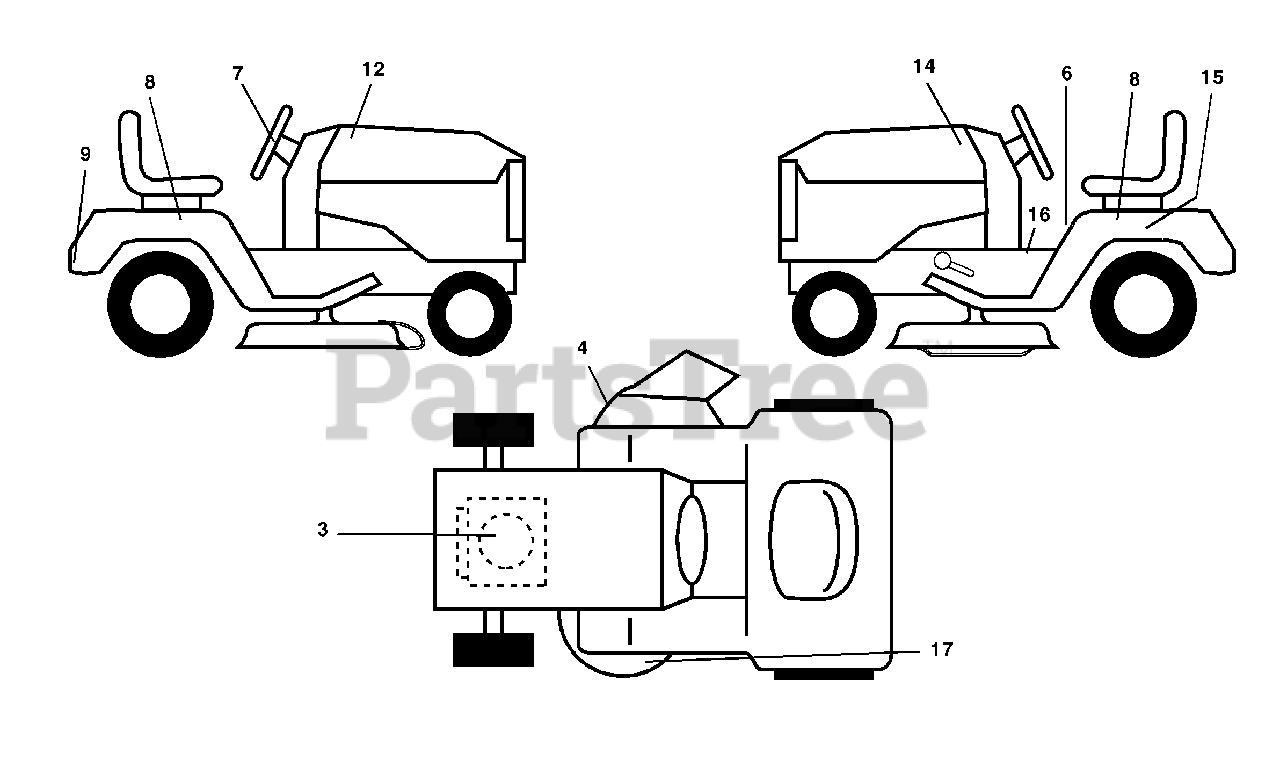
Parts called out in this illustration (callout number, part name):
3	Decal, Engine HP
4	Decal Warning
6	Decal, Fender Danger English
7	Decal Ins Str Wh
8	Decal, Fender 5 Sp.
9	Decal Fender
12	Decal, Hood RH
14	Decal, Hood LH
15	Decal, Caution, Battery
16	Decal, Oper Inst.
17	Decal, V-Belt Sch.
17	Decal, Handle Lft Height Adj.
